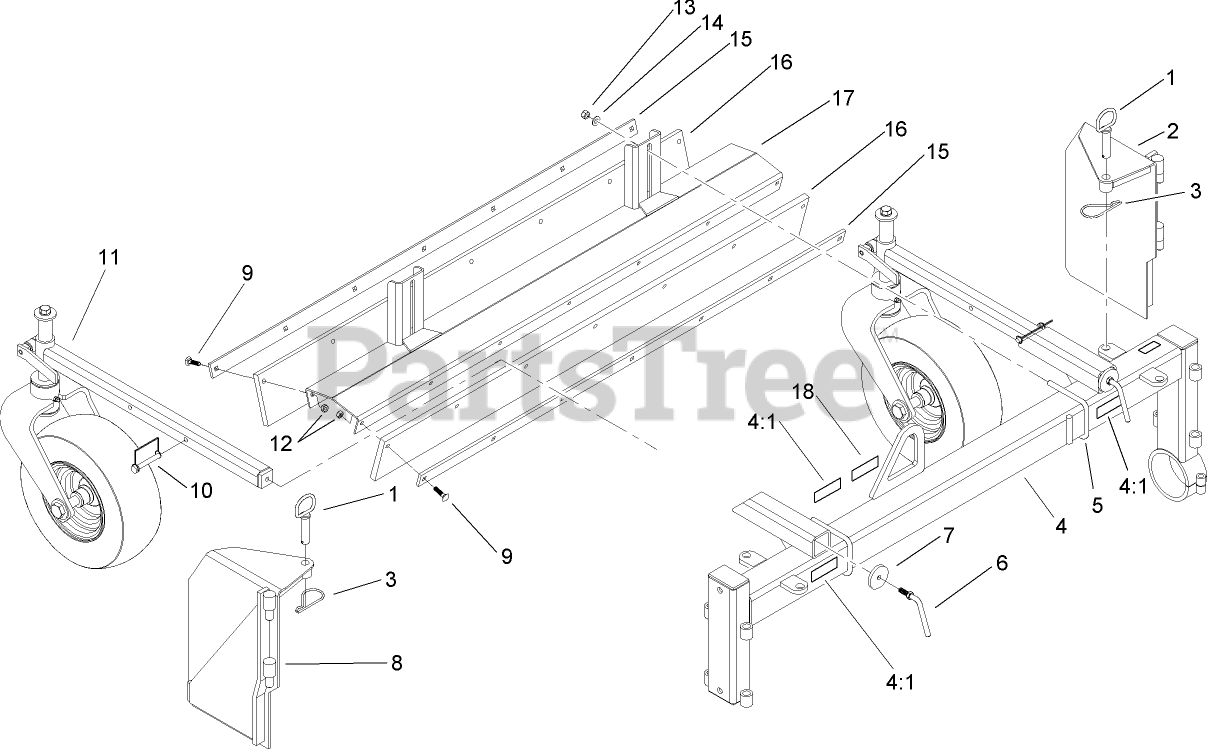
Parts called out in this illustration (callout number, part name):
1	PIN ASSEMBLY
2	BRACKET-GATE, RH
3	PIN-HAIR
4	FRAME-MAIN, RAKE
4:1	DECAL-DANGER
5	U-BOLT
6	HANDLE-ARM, CASTOR
7	WASHER-FLAT
8	BRACKET-GATE, LH
9	SCREW-CARR
10	PIN-HITCH
11	CASTOR WHEEL ASM
12	NUT-LOCK, CONE
13	NUT-LOCK, NI
14	WASHER-HARDENED
15	STRAP-BARRIER
16	BARRIER-RAKE
17	MOUNT-BARRIER
18	DECAL
